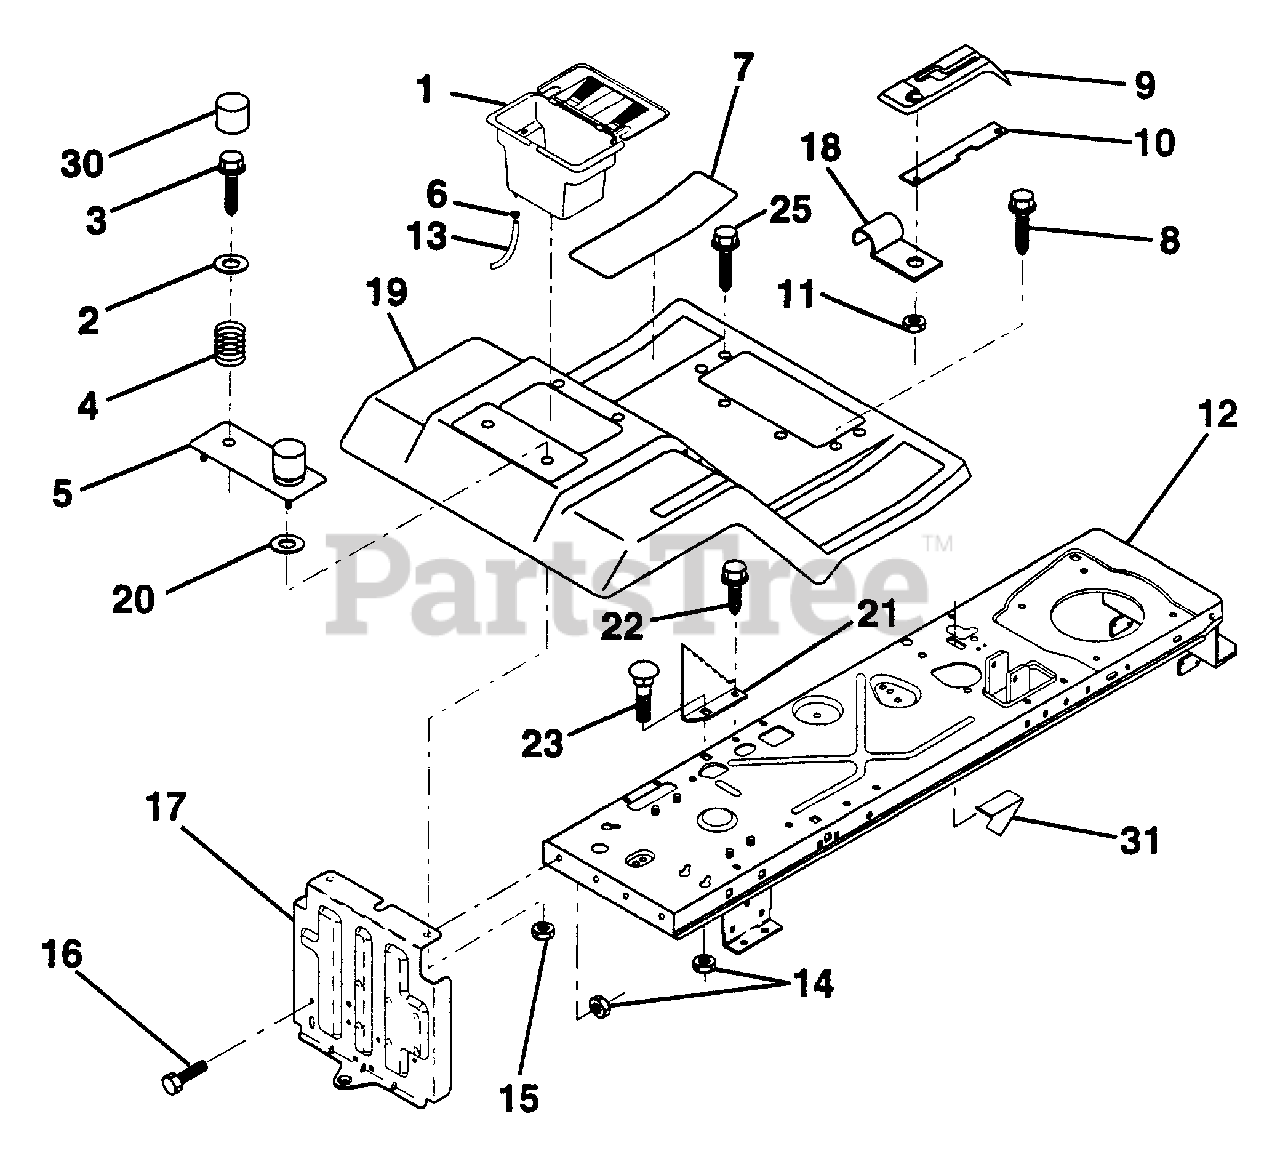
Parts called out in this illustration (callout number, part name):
1	Case Asm. Battery
2	Washer 13/32 x 1-1/4 x 12 Ga.
3	Screw Thdrol. 3/8-16 x 3/4
4	Spring seat
5	Plate Asm. Pnt Battery Fender
6	Clamp Hose Olive
7	Pad Footrest Rubber Deluxe
8	Screw Thdrol. 5/16-18 x 3/4
9	Console Shf. 6sp W/Ign.
10	Plate Lock Shift
11	Nut Self Thd. Wsh-Hd 1/4
12	Chassis Asm. Weldment
13	Tube Plastic
14	Nut Crownlock 5/16-18
15	Nut Keps Hex 1/4-20
16	Bolt Hex Hd. 5/16-18 x 3/4
17	Drawbar Asm.
18	Clip Insulated
19	Fend/Foot Asm. Pnt Shf. Fnd.
20	Washer 9/32 x 7/8 x 13 Ga.
21	Bracket Stop Depth
22	Screw Thdrol 5/16-18 x 1/2
23	Bolt Rdhdsqnk. 5/16-18 x 3/4
25	Scr-Hex Wsh Rol 5/16-18 x 1
30	Cap Spring Seat
31	Switch Actuator
